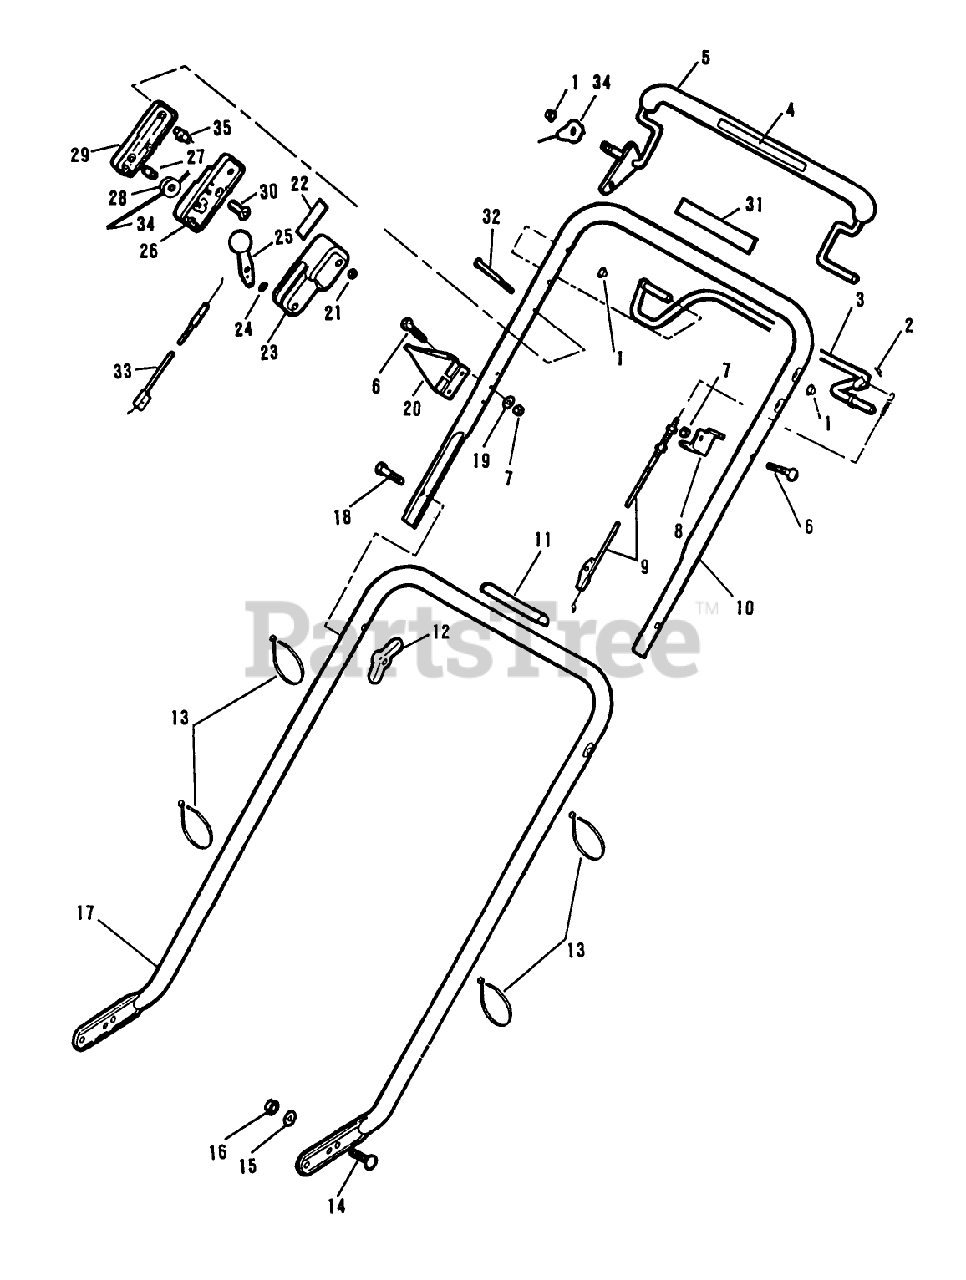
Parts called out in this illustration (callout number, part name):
5	CONTROL LEVER ARG
7	LOCKNUT E
8	ANCHOR C'DUIT TRO
9	CABLE - CONTROL
12	NUT-WING
16	NUT WING
19	WASHER
21	NUT C/LOCK E
24	WASHER-SPRING
25	LEVER&KNOB AY WES
27	PIN SKF
28	PULLEY PL
29	OUTER CONTROL CASE
30	SCREW
32	SCREW
33	CABLE TH'TTLE WES
34	CONTROL CABLE
35	COLUMN
